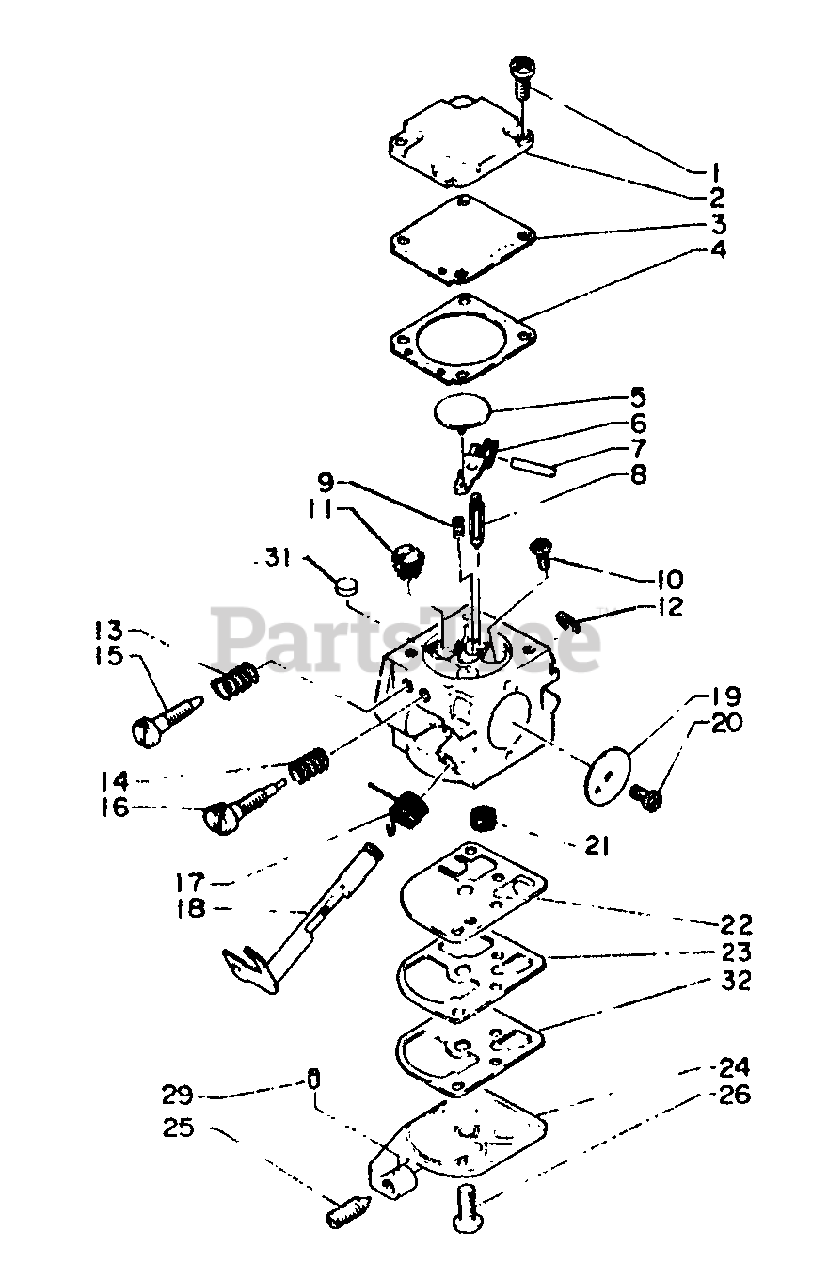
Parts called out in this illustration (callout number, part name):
1	SCREW
2	COVER, METERING
3	DIAPHRAGM, METERING
4	GASKET, DIAPHRAGM
5	PLUG, WELCH
6	LEVER, METERING
7	PIN, METERING LEVER
8	VALVE, INLET NEEDLE
10	SCREW, METERING LEVER PIN
11	NOZZLE, CHECK VALVE
12	RING, RETAINING
15	NEEDLE - HIGH SPEED
16	NEEDLE - LOW SPEED
17	SPRING, RETURN
18	SHAFT, THROTTLE
19	VALVE, THROTTLE
21	STRAINER
22	DIAPHRAGM, PUMP
23	GASKET, PUMP
24	BASE, PURGE
25	SCREW, IDLE ADJUST
26	SCREW, PUMP COVER
29	PIECE, FRICTION
31	PLUG, WELCH
32	DIAPHRAGM, SURGE
